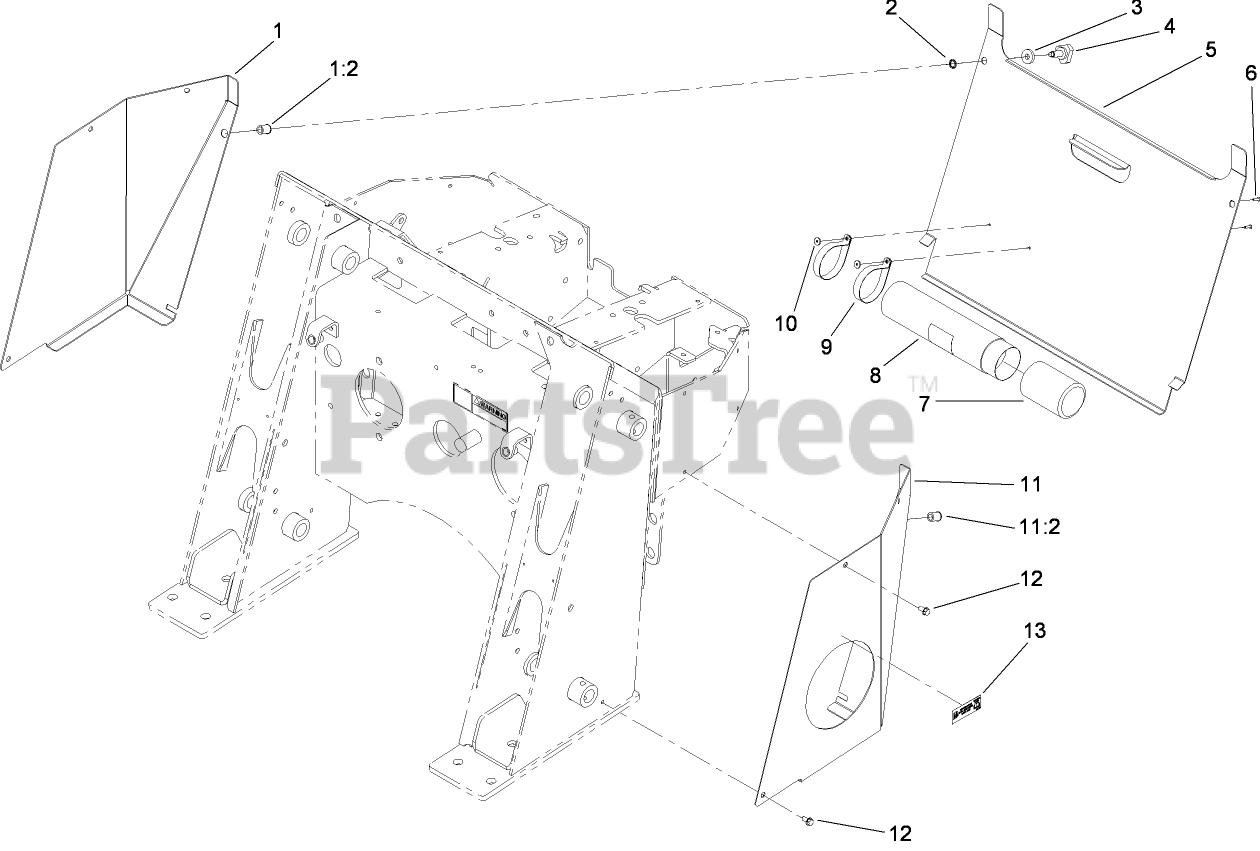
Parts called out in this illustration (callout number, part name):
1	RH REAR COVER SUPPORT ASM
1:2	INSERT-NUT
2	RING-RETAINING
3	WASHER-RUBBER
5	COVER-ACCESS, REAR
6	RIVET-POP
7	CAP-HOUSING
8	TUBE-MANUAL
9	CLAMP-R
10	WASHER-BACK
11	LH REAR COVER SUPPORT ASM
11:2	INSERT-NUT
12	SCREW-HWH
13	DECAL-LOW SULFUR
